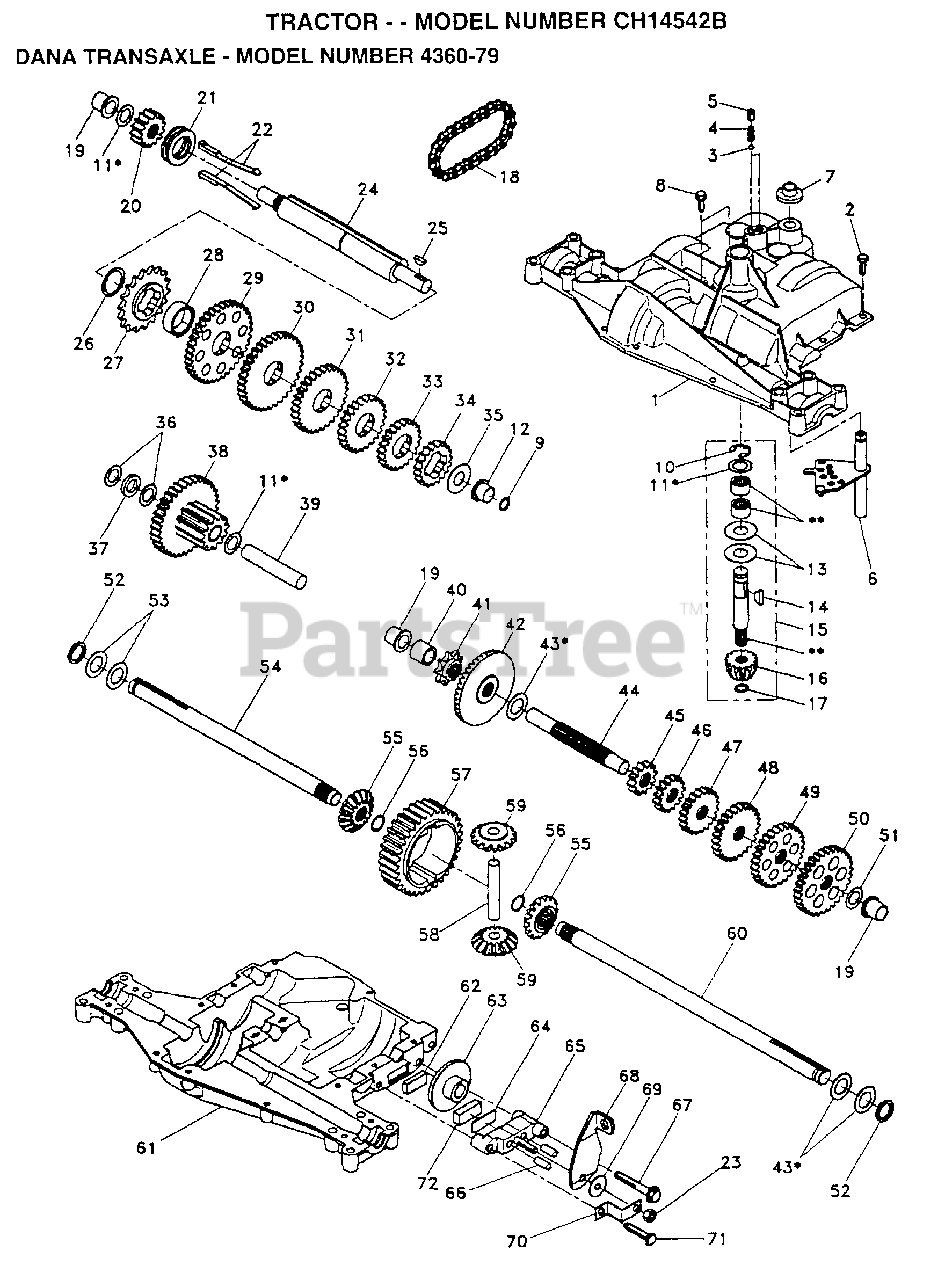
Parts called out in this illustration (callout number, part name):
1	HOUSING UPPER TRN
4	"SPRING, DETENT LT"
5	"SCREW, SET LT"
6	KIT SHIFTER ASM
7	SHIFTER BOOT
8	SCREW TAP W/SEAL
9	SQUARE RING
11	ASM KIT SHIM 4689
12	BEARING FLAN-DANA
13	WASHER T
14	KEY WOODRUFF-DANA
15	AS KIT INPUT SHFT
16	PINION 14T T
17	"RING,RETAINING LT"
18	"CHAIN,24 PTCH LT"
19	BEARING.FLNG.5510
20	GEAR SPUR 14 TTH
21	COLLAR CLUTCH
22	ASM KIT CLTCH KEY
23	NUT.LOCK.5/16-24
24	SHAFT INTERM DANA
25	WOODRUFF KEY
26	"RING,RETAINING LT"
27	SPROCKET 18T T
28	SPACER YT
29	GEAR SPUR 37 TTH
30	GEAR SPUR 35 TTH
32	GEAR 25T LT
33	GEAR SPUR 22 TT
34	SPUR GEAR 19T
35	"WASHER, PLAIN LT"
36	WASHER 025
37	SPACER
38	ASSM GEAR COMB
39	SHAFT IDLER
40	SPACER T
41	SPROCKET 9T LT
43	ASM KIT SHIM
44	SHAFT T
45	GEAR SPUR 12 TTH
46	GEAR SPUR 15 TTH
48	"GEAR, SPUR 25T LT"
49	GEAR 28T T
50	"GEAR, SPUR 31T LT"
51	WASHER 060
52	NEOPRENE WASHER
53	WASHER 031
55	GEAR 15T T
56	"RING,RETAINING LT"
58	SHAFT T
59	GEAR 1ST T
61	HOUSING LOWER TNS
62	PUCK T
63	BRAKE DISC. T
64	SPACER LT
66	PIN T
69	WASHER LT
71	"SCREW, TAPPING LT"
72	PUCK T
